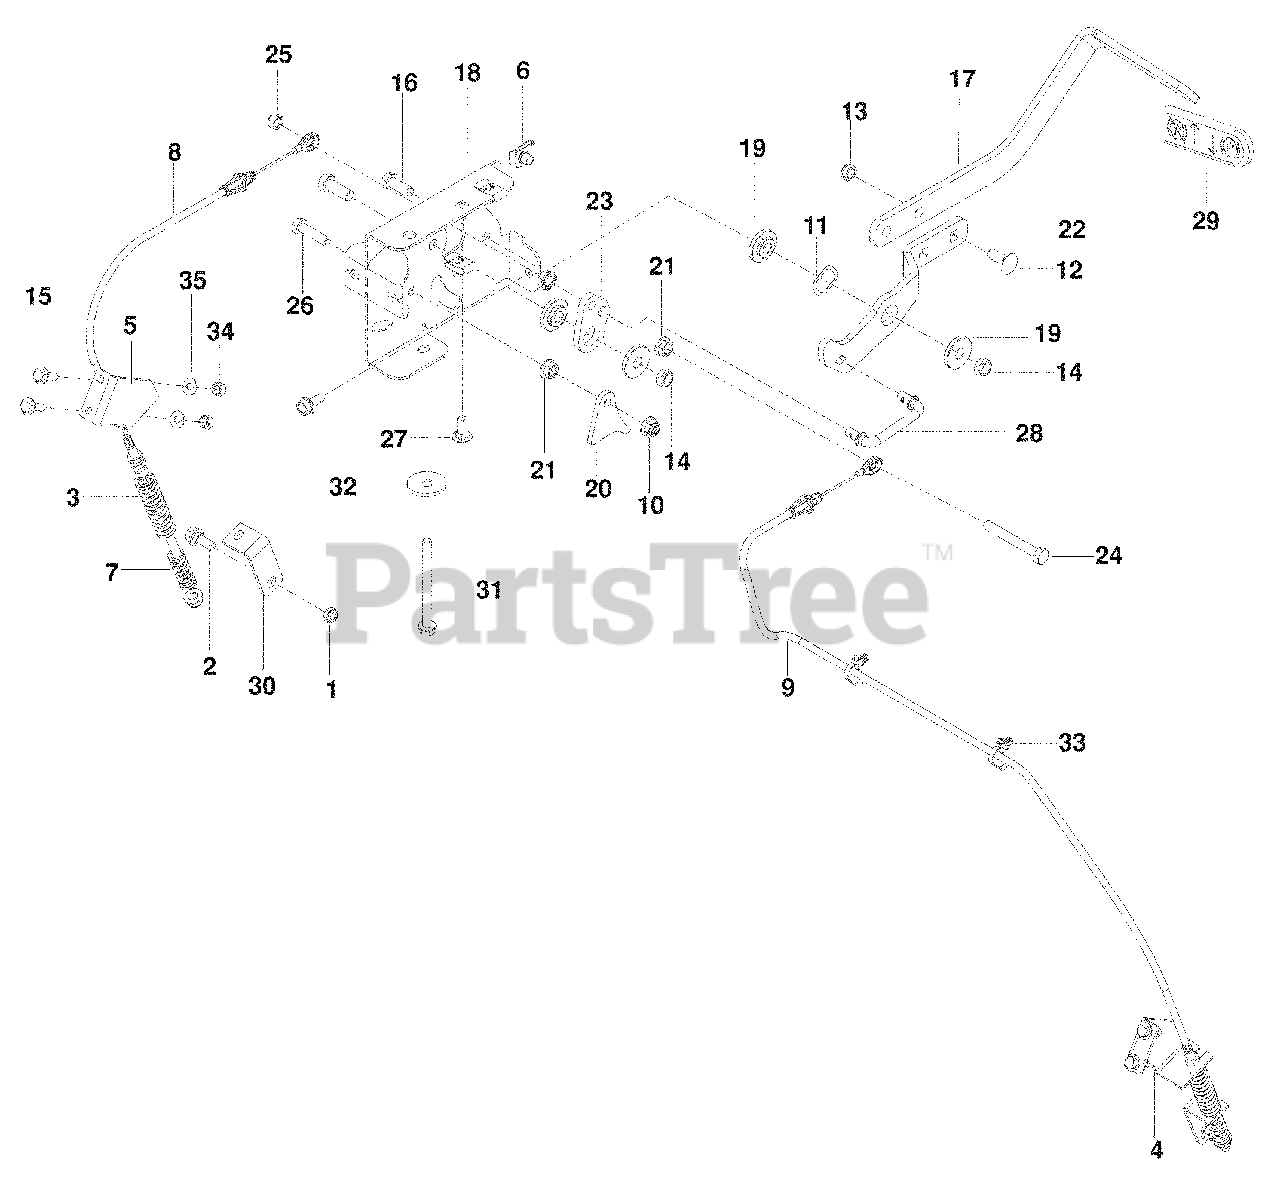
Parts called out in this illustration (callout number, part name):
1	NUT 5/16 HEX NYLOC
2	BOLT 5/16 SHOLDER
3	SPRING, RETURN
4	BRACKET, RT
5	BRACKET, LT
6	RETAINER, U TYPE
7	SPRING, ENGAGEMENT
8	CABLE, BRAKE, SHORT
9	CABLE, BRAKE, LONG
10	NUT 5/16-18 FLANGE NYLOC
11	WASHER .825 WAVE
12	BOLT, RD HD 3/8-16 x 1
13	NUT 3/8-16 HEX FLG NYLOC
14	NUT 3/8-16 HEX JAM NYLOC
15	HCS ¼-20 x 7/8
16	BOLT, HEX 3/8-16 x 1
17	ARM, BRAKE
18	MOUNT, BRAKE
19	BUSHING, BRAKE
20	ACTUATOR, SWITCH
21	NUT 5/16-18 HEX WHIZLK
22	LEVER, BRAKE
23	BELLCRANK, BRAKE
24	BOLT, HEX 5/16-18 x 2½ TPBLT
25	NUT 5/16-18 HEX NYLOC
26	BOLT, HEX 5/16-18 x 1
27	BOLT, RD HD 5/16-18 x ¾
28	LINKAGE, BRAKE
29	GRIP, BRAKE HANDLE
30	BRACKET, BRAKE
31	HHFS 5/16-18 x 3¾
32	WASHER ½ FLAT
33	TIE, w/ CLIP
34	NUT ¼-20 HEX NYLOC
35	WASHER ¼ FLAT SAE
